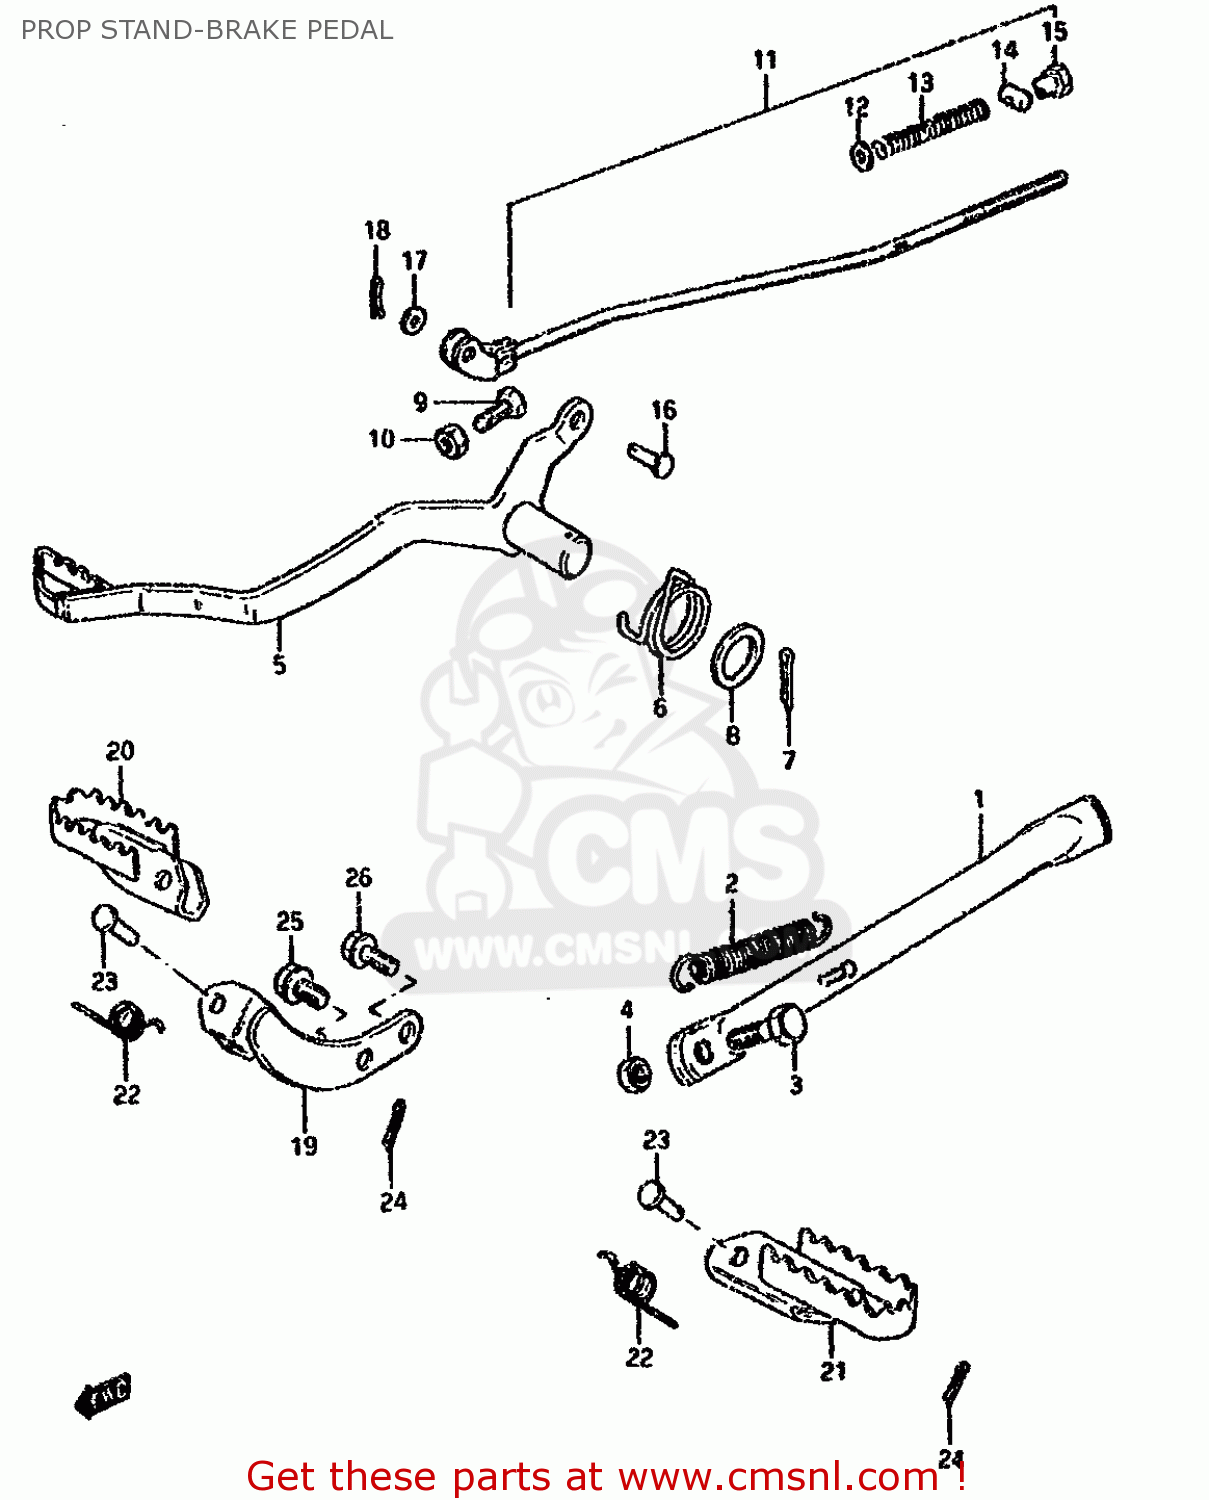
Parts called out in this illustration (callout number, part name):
1	STAND,SIDE
2	SPRING
3	BOLT
4	NUT
5	PEDAL,BRAKE
6	SPRING
7	COTTER PIN
8	WASHER(15.5X26X2.3)
9	BOLT(6X23)
10	NUT
11	ROD ASSY,RR BRAKE
12	WASHER
13	SPRING
14	PIN(11X18)
15	NUT (6MM)
16	PIN(L:13.5)
17	WASHER
18	PIN 20X20
19	BAR,FRONT FOOTREST
20	FOOTREST,FR,R
21	FOOTREST,FR,L
22	SPRING
23	PIN
24	PIN 20X20
25	BOLT
26	BOLT
